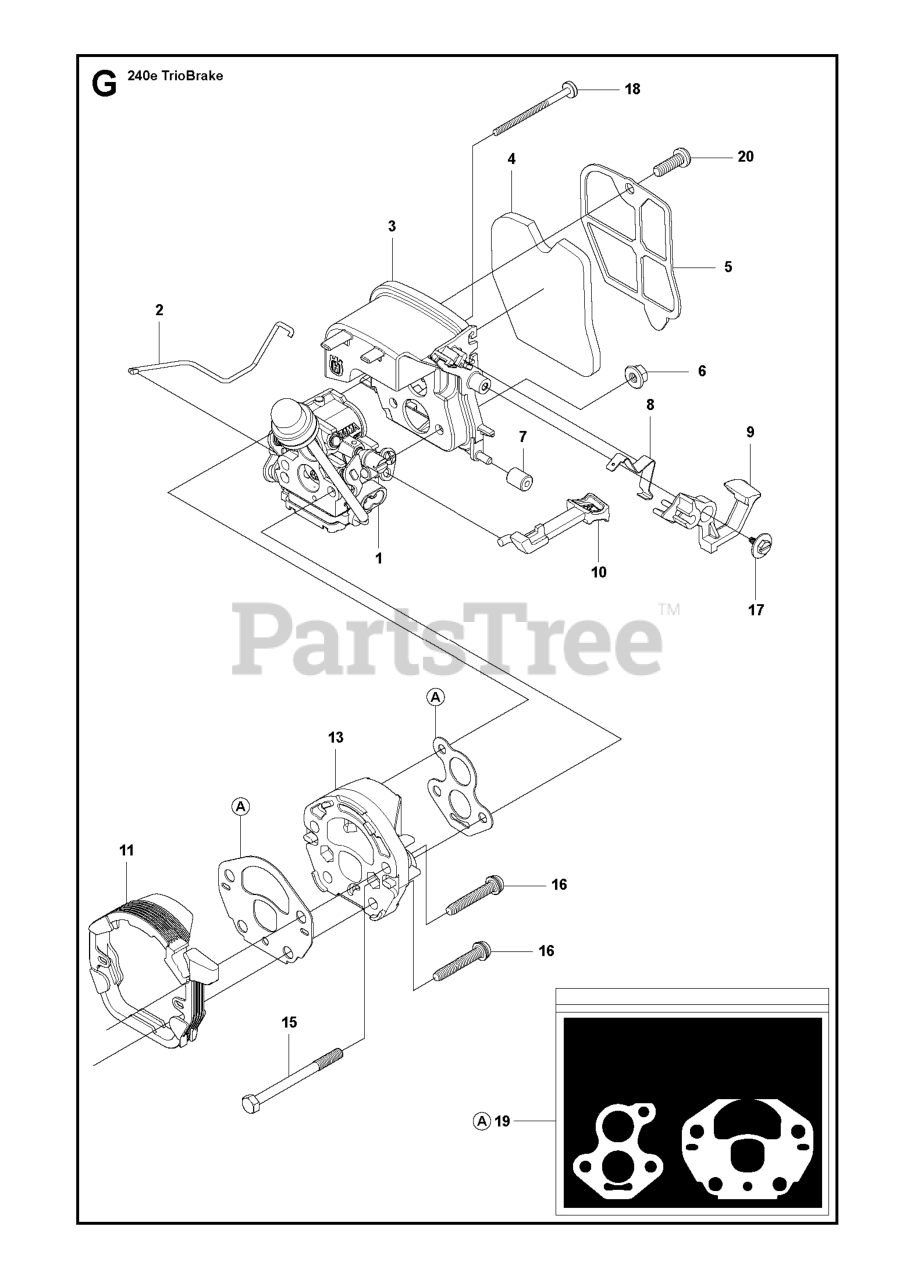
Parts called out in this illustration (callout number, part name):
1	CARBURETTOR 14MM AIR BORE, ANG
2	THROTTLE WIRE
3	FILTER HOUSING
4	AIR FILTER
7	ISOLATOR FILTER HOUSING
9	SWITCH LEVER
10	CHOKE KNOB
11	CARB ADAPTOR SEAL
13	CARB ADAPTOR
15	STUD CARBURETOR
18	TOP STUD - CARBURETOR
19	GASKET KIT
20	SCREW FILTER PLATE
